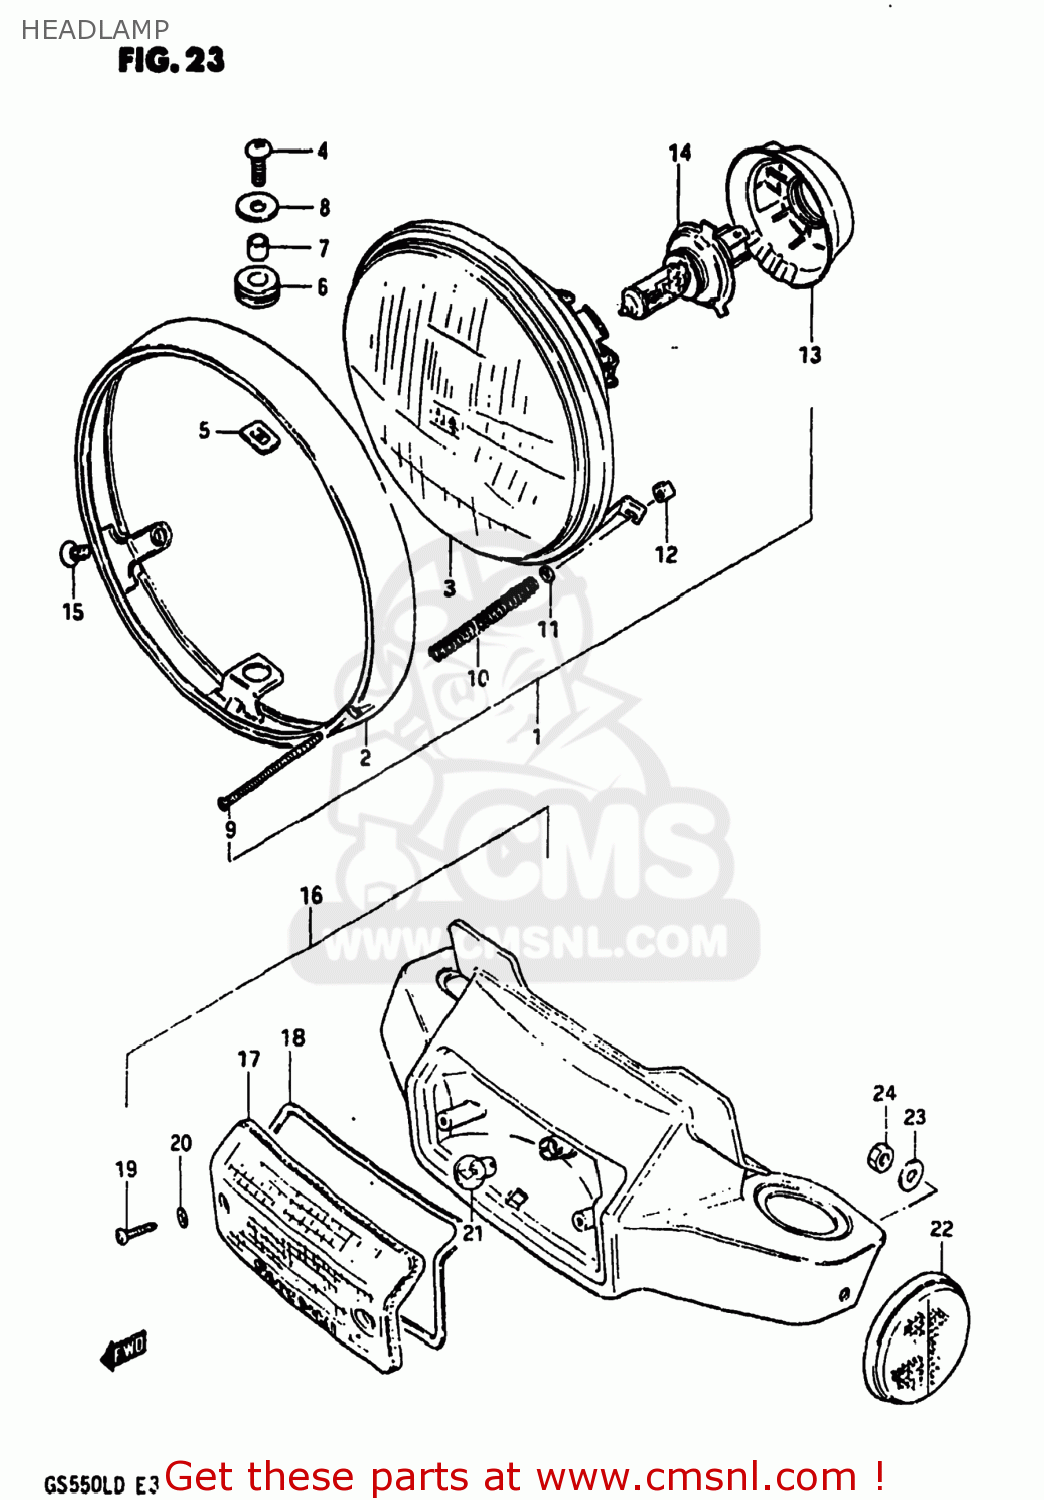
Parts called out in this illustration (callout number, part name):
1	LAMP ASSEMBLY,HEAD
2	RIM,HEAD LAMP
3	LAMP UNIT
4	SCREW(5X14)
5	NUT
6	CUSHION
7	SPACER
8	WASHER
9	SCREW,HEADLAMP ADJUST
10	SPRING,HEADLAMP ADJUST
11	WASHER
12	NUT
13	COVER,SOCKET
14	BULB(12V60/55W,H4)
15	SCREW(5X12)
16	LAMP ASSEMBLY,FRONT POSITION
17	LENS
18	GASKET,POSITION LAMP
19	SCREW,POSITION LENS
20	GASKET (NAS)
21	BULB
22	REFLEX REFLECTOR ASSEMBLY
23	WASHER
24	NUT
